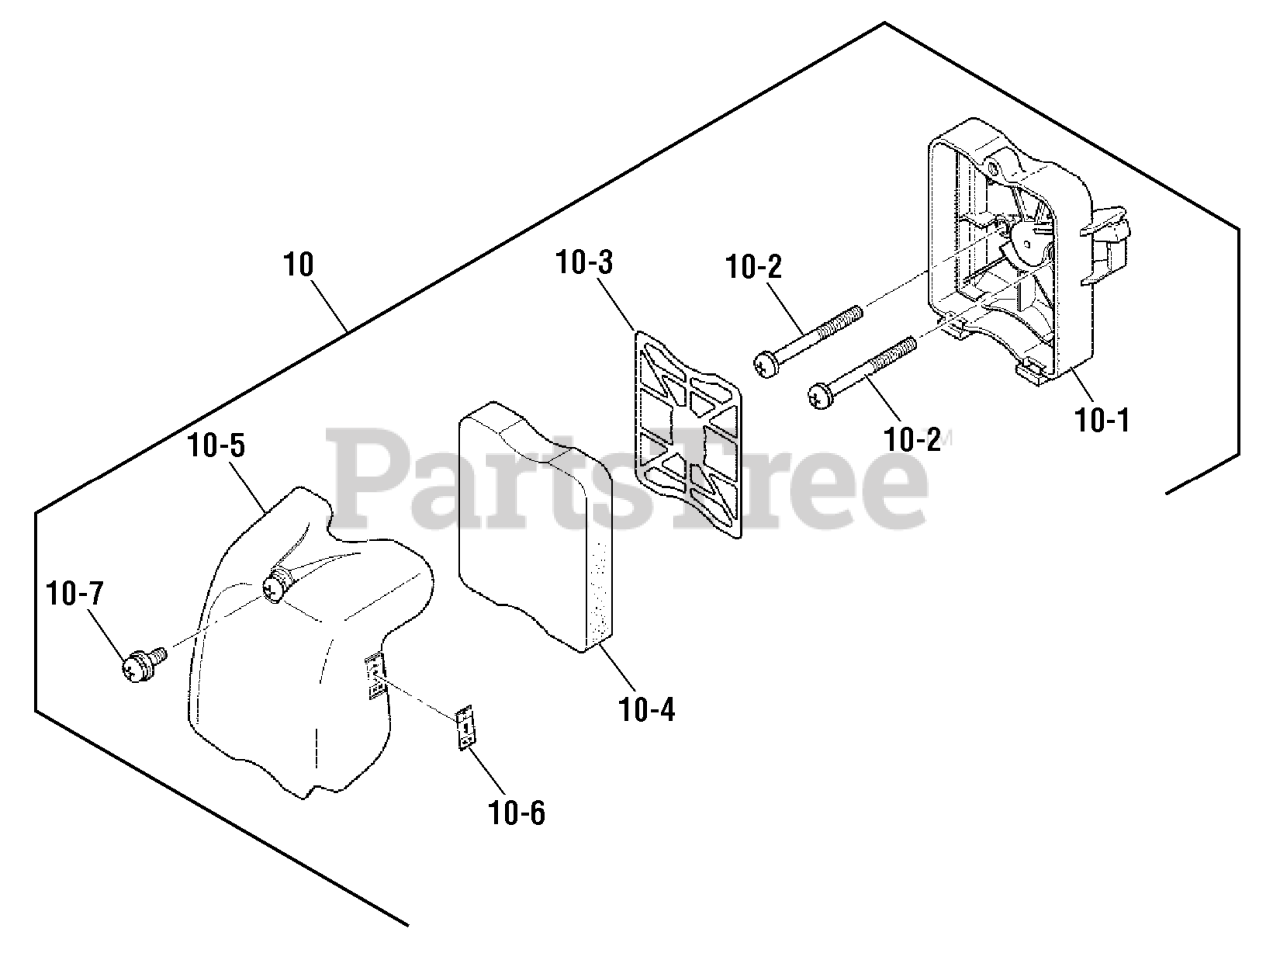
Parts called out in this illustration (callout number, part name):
10	AIR CLEANER ASSEMBLY
10-1	CLEANER CASE ASSEMBLY
10-2	SCREW & WASHER
10-3	GRID
10-4	ELEMENT
10-5	CLEANER COVER ASSEMBLY
10-6	LABEL
10-7	SCREW & WASHER
